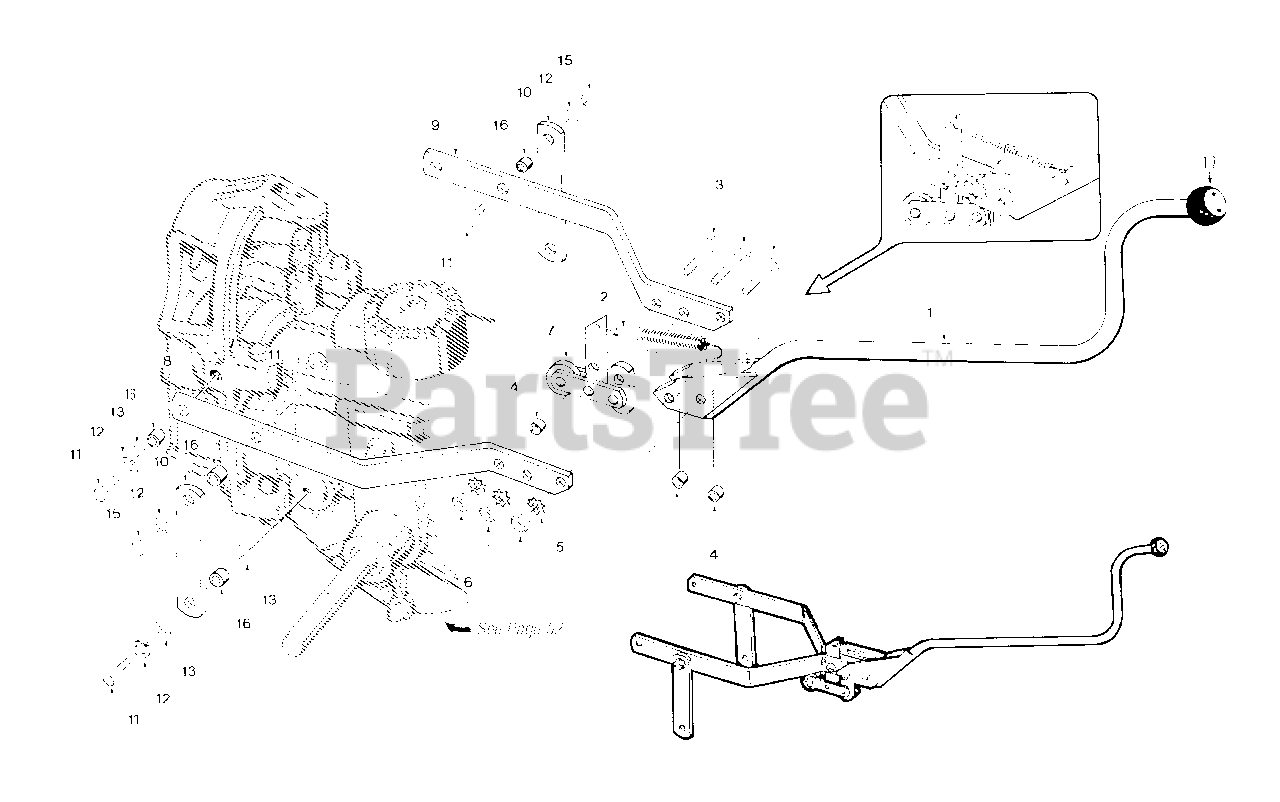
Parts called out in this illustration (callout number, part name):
1	Lever-Wheels/Tines/PTO Drive
2	Spring-clutch pawl
3	Bolt-hex hd., 5/16-18 x 1-1/2"
4	Bushing-3/8"
5	Lockwasher-external tooth, 5/16"
6	Nut-hex, 5/16"-18
7	Roller Assembly
8	Yoke-left side
9	Yoke-right side
10	Link-Yoke pivot, left & Right 6-7/8" long
11	Bolt-hex hd., 3/8-16 x 1"
12	Lockwasher-spring lock, 3/8"
13	Washer-flat, 3/8", S.A.E.
15	Nut-hex, 3/8"-16
16	Bushing-spacer, 19/64" (.300")
17	Knob-not avail. separately.
